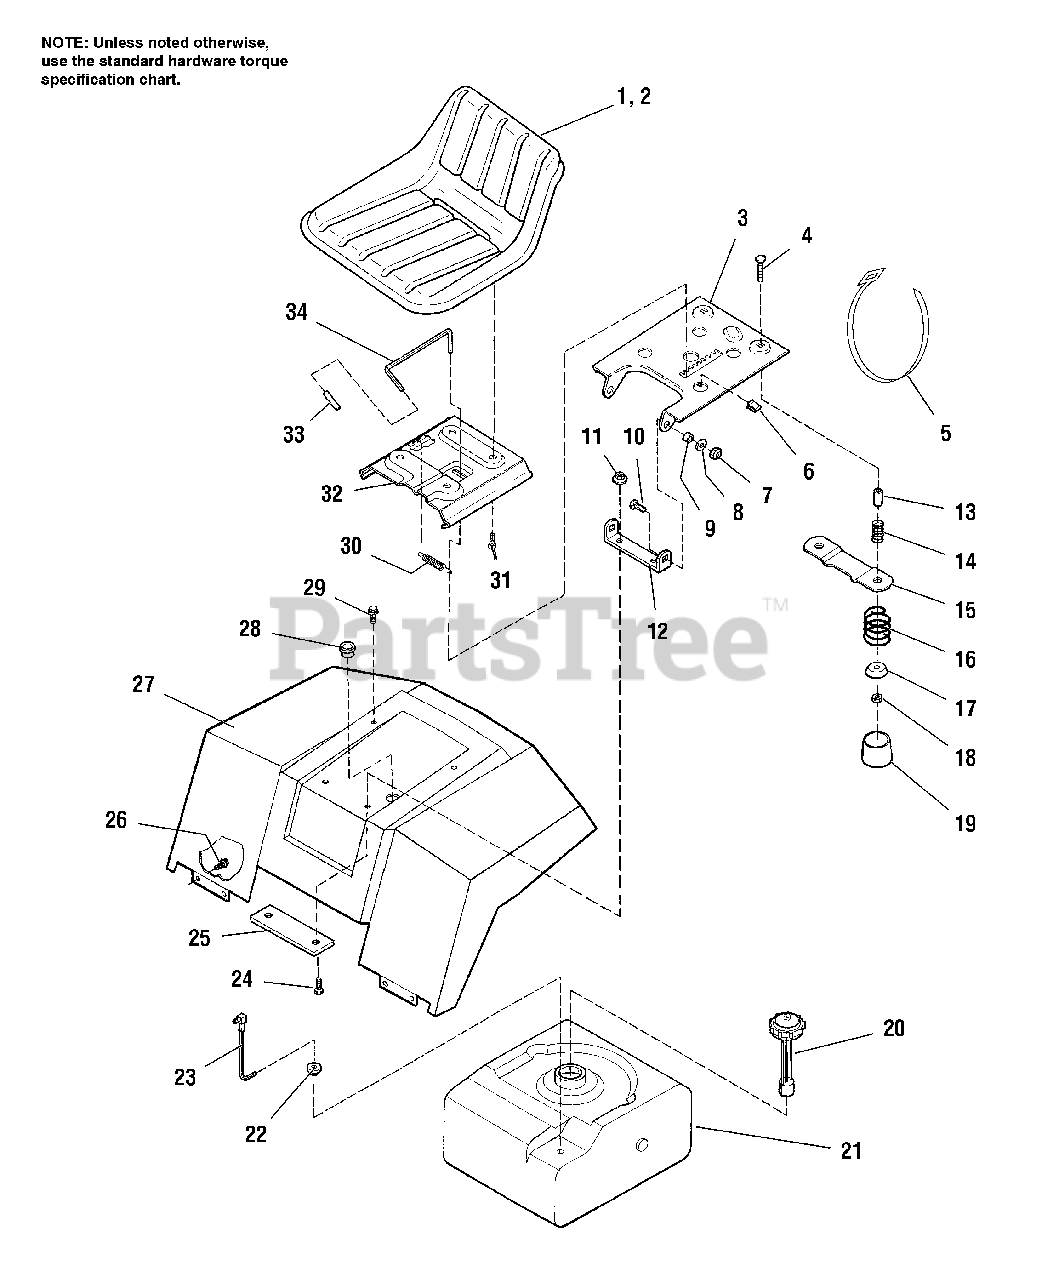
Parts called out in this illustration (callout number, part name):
1	SEAT, High-Back
2	COVER, High-Back Seat
3	SUPPORT, Seat Pivot
4	CARRIAGE BOLT, 5/16-18 x 2
5	TIE, Self-locking, 15" long
6	CLIP, Speed
7	NUT, Hex, Nylon Lock, 3/8-16
8	WASHER, Plain, 13/32
10	CARRIAGE BOLT, 3/8-16 x 1
11	NUT, Hex, Flange, Whizlock, 5/16-18 x 1/2
12	BRACKET, Seat Pivot
14	SPRING, Compression
15	PLATE, Switch
16	SPRING, Compression
17	WASHER, Plain
18	NUT, Hex, Nylon Lock, 5/16-18
19	COVER, Spring
20	CAP, Fuel Gauge
21	TANK, Fuel
23	ELBOW & TUBE ASSY.
24	SCREW, Truss Hd., Torx drive, 3/8-16 x 1
25	PLATE, Reinforcement
26	SCREW, Taptite, 1/4-20 x 1/2
27	SEAT DECK, Orange
27	SEAT DECK, Red
28	BUSHING, Snap
29	SCREW, Taptite, 5/16-18 x 5/8
30	SPRING, Extension
31	BOLT, Hex, Whizlock, 5/16-18 x 5/8
32	BRACKET, Seat Slide
33	HANDLE, Grip
34	LEVER, Seat Release
